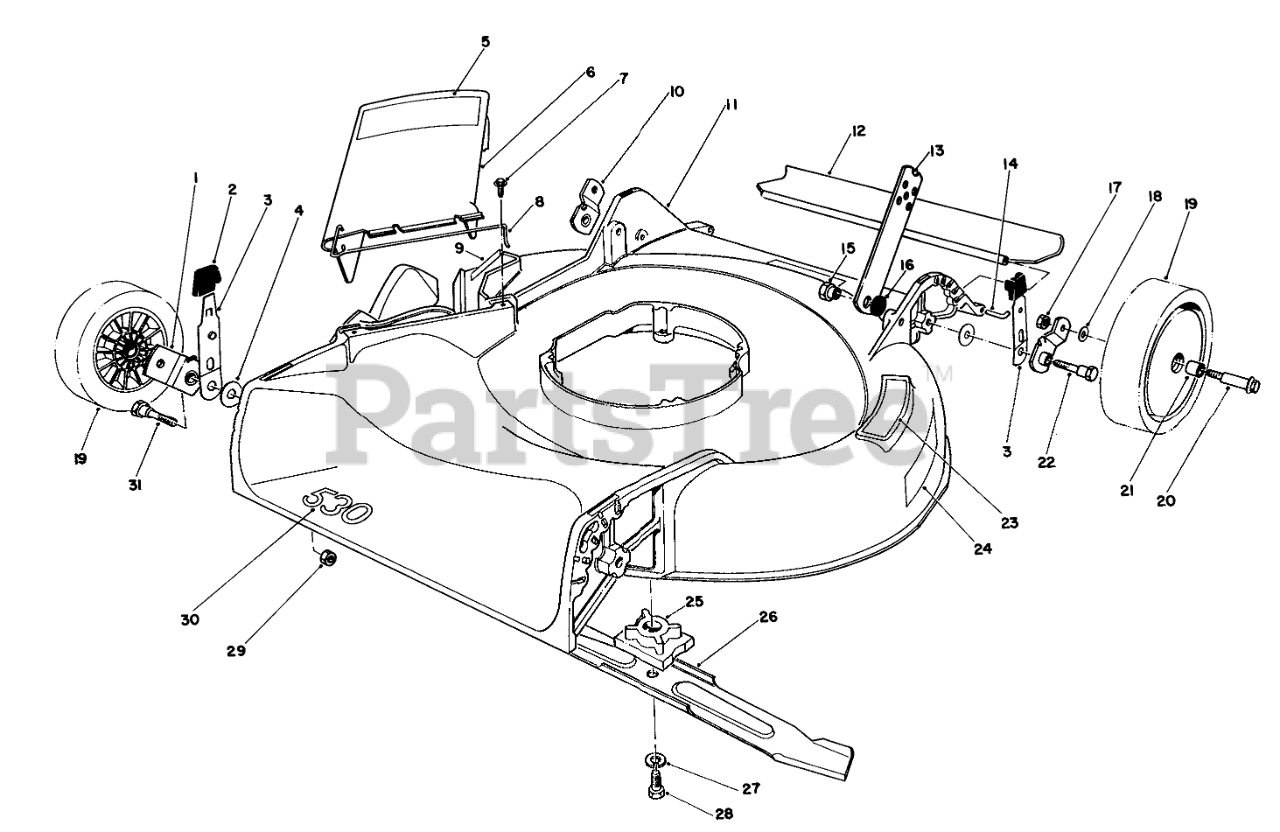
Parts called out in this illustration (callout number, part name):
1	Pivot Arm
2	KNOB-ARM
3	SPRING ARM ASM
4	Washer
5	Decal-Danger(French)
6	Deflector Assy. (Incl. Ref. #5&8)
7	SCREW-HWH
8	SPRING HINGE
9	Decal-Danger
10	Pivot Arm
11	HOUSING/DECAL
12	Rear Shield
13	HANDLE LATCH
14	SHIELD ROD
15	HANDLE PIVOT NUT
16	SPACER
17	NUT-LOCK
18	WASHER
19	Wheel & Tire Assembly (Incl. Ref. #21)
20	WHEEL BOLT
21	BUSHING
22	PIVOT SCREW
23	STEP PAD DECAL
24	Decal-Step
25	BLADE RETAINER
26	Blade
27	WASHER-LOCK
28	SCREW-HH
29	NUT-LOCK, NI
30	Decal-530
31	PIVOT SCREW
